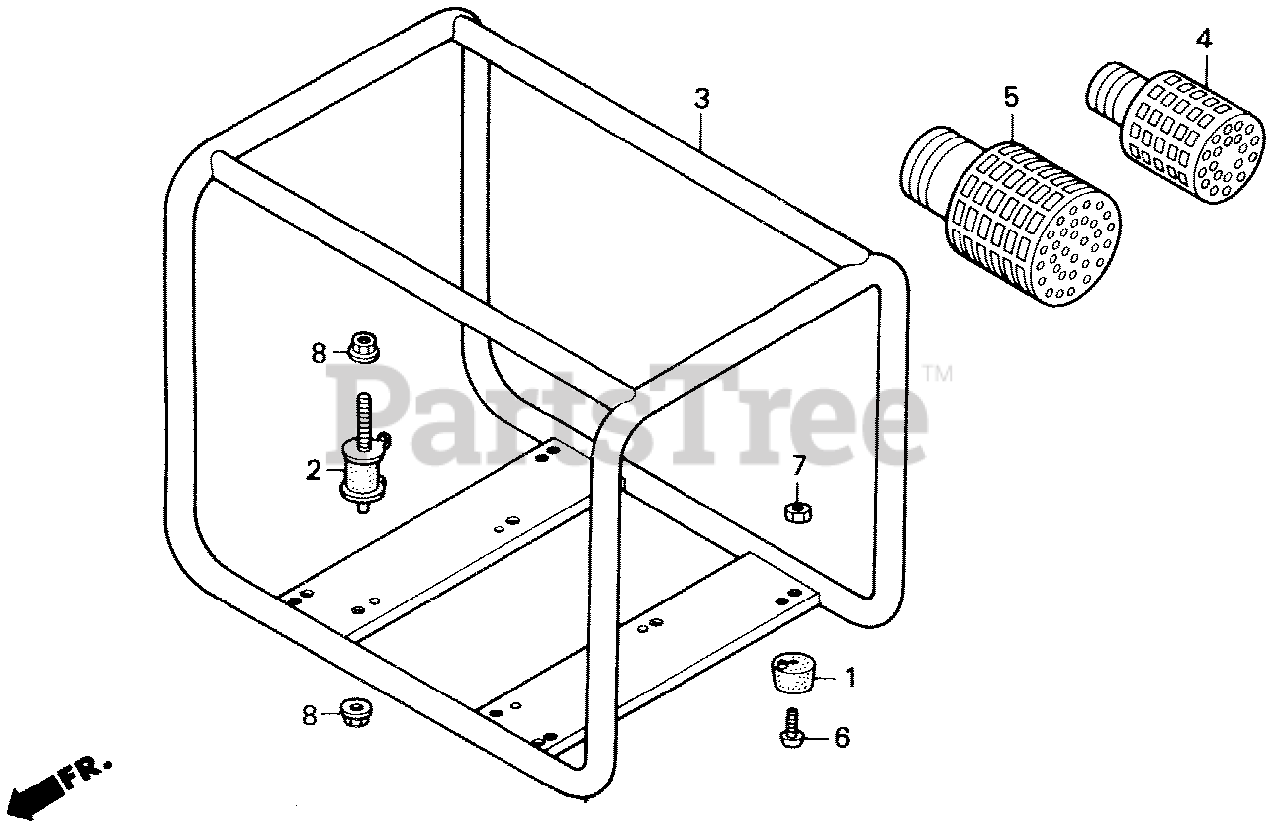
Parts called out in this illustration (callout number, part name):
1	RUBBER (LOWER)
2	RUBBER, ENGINE MOUNTING
4	STRAINER
6	SCREW, PAN (6X10)
7	NUT, HEX. (6MM)
8	NUT, FLANGE (8MM)
